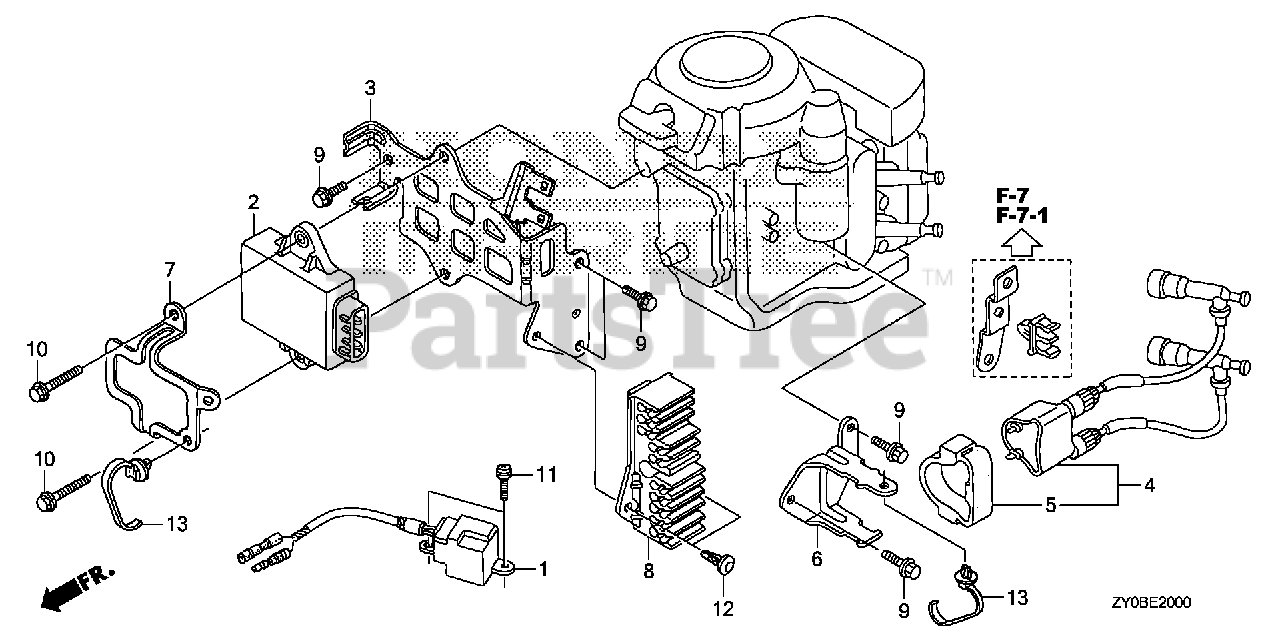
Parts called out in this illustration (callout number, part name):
1	COIL ASSY., PULSER
2	MODULE, IGNITION CONTROL (CDI)
3	PLATE, C.D.I.
4	COIL ASSY., IGNITION
5	SUSPENSION, IGNITION COIL
6	BRACKET, IGNITION COIL
7	BRACKET, C.D.I.
8	BRACKET, CONNECTOR
9	BOLT, FLANGE (6X14) (CT200)
10	BOLT, FLANGE (6X25)
11	SCREW-WASHER (5X16)
12	CLIP, ANCHOR
13	CLIP, HARNESS BAND (151.5MM) (NATURAL)
